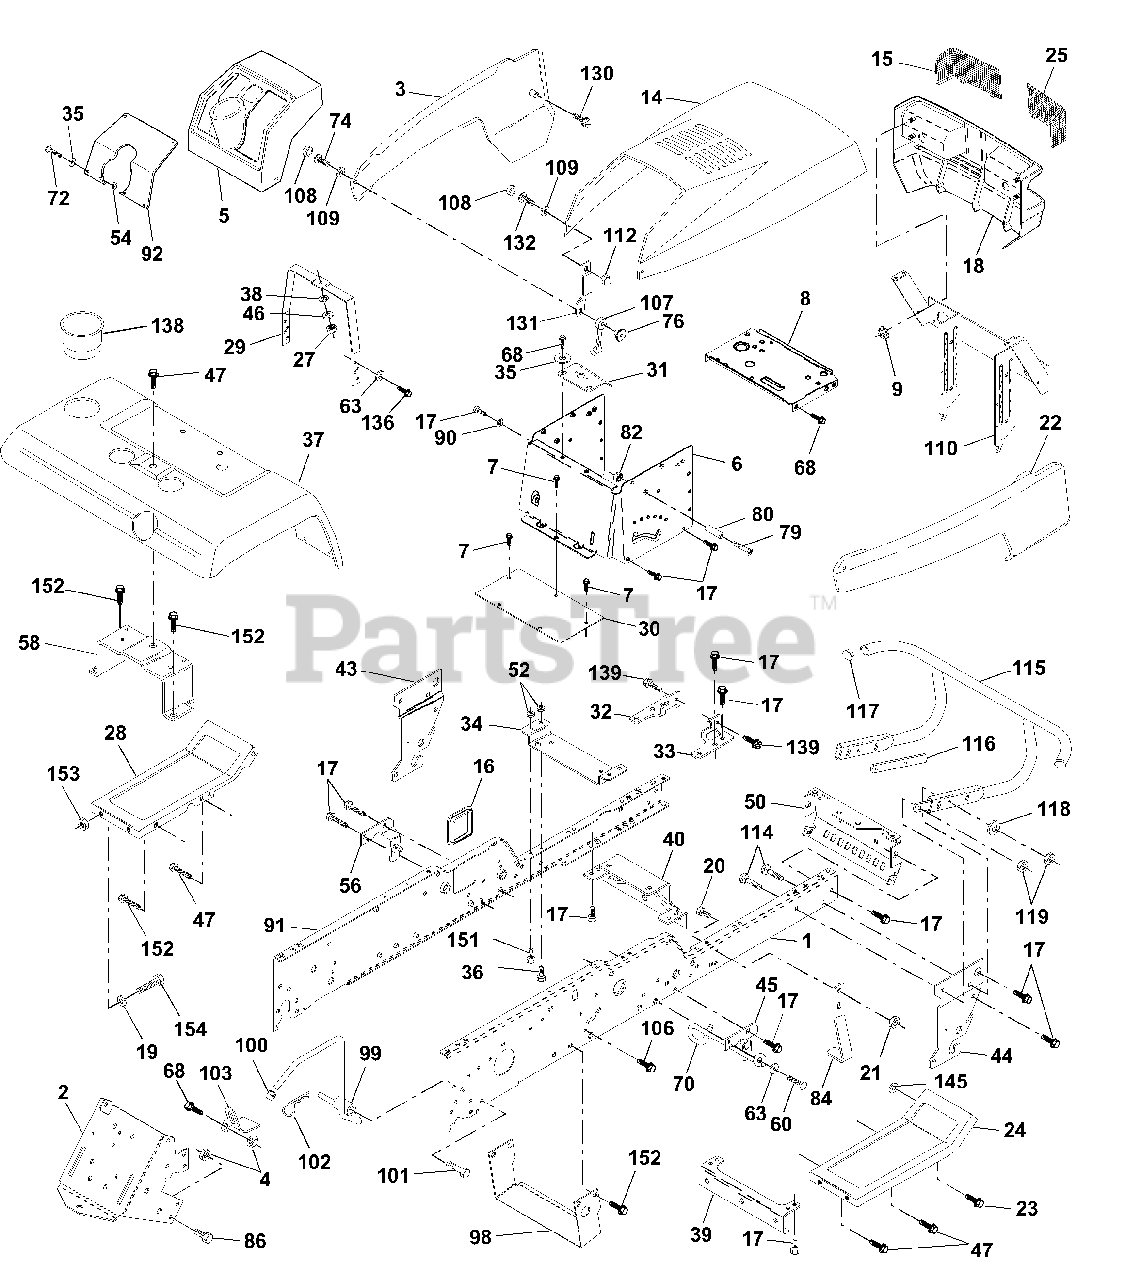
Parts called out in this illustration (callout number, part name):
1	Rail, Frame RH
2	Drawbar, Gt
3	Panel Asm., Side LH
4	Nut, Crownlock 7/16-14 Unc
5	Dash, Plastic Black
6	Dash 1-PCS, Lower
7	Screw, Thd Cut 1/4-20 x 1/2
8	Support, Battery
14	Hood Asm., Pnt
15	Lens, Headlight LH
16	Cover, Access
17	Screw 3/8-16 x 3/4
19	Washer 13/32 x 13/16 x 12 Ga.
20	Bolt, Fin Hex 3/8-16 x 1
21	Nut, Crownlock 3/8-16 Unc
22	Panel Asm., Side RH
23	Screw 3/8-16 x 1/2
24	Footrest, RH
25	Lens Headlight RH
27	Nut Fin Hex 1/4-20
28	Footrest, LH
29	Bracket, Support Dash
31	Brace, Support Steering
32	Bracket Asm., Frame Pivot Lh
33	Bracket Asm., Frame Pivot Rh
34	Bracket, Engine Support Rear
35	Washer 11/32 x 11/16 x 16 Ga.
36	Bolt, Fin Hex 5/16-18 x 3/4
37	Fender, Pnt.
38	Washer, Lock 1/4
39	Bracket, Axle Front
40	Bracket, Support Axle/Engine
43	Bracket, Spnsn Front Lh
44	Bracket, Spnsn Front Rh
45	Bracket Asm., Susp Chassis Rh
46	Washer 9/32 x 3/4 x 16 Ga.
47	Screw Thdrol 3/8-16 x 1/2
50	Bracket, Chassis Front
52	Locknut, Hex W/Ins 5/16-18 Unc
54	Nut 5/16-18
56	Bracket Asm., Susp Chassis Lh
58	Bracket Asm., Fender
60	Screw 3/8-16 x 1-1/4
63	Washer 13/32 x 1 x 14 Ga.
68	Screw, Thdrol 5/16-18 x 1/2
70	Guide, Belt Mid Span
72	Screw, Mach Trhd 5/16-18 x 3/4
74	Screw, Machine #10-24
76	Nut, Weld #10-24
79	Screw, Machine #10-24 x 1/4
80	Spacer, Split
82	Nut #10-24
84	Stop, Over Center 44" 20/23" T. 94
86	Bolt, Fin Hex 7/16-14 Unc x 1
90	Washer, Lock External Tooth 3/8
91	Rail, Frame Lh
92	Plate, Silkscreen Dash
98	Bracket Chassis Skid
99	Rod Asm. Bypass
100	Cap Brake Parking Black
101	Screw Thdrol. 3/8-16 x 1-3/4
102	Retainer Spring 1"
103	Bracket Lock Bypass
106	Screw Thdrol. Hex Hd Zinc Mur
107	Latch, Chute Blk
108	Cap, Snap Black
109	Cap, Washer Snap
110	Pivot Asm. Grille/Hood Husq. VGT
112	Nut, Acorn, Hex #10-24
114	Bolt, Carriage 3/8-16 x 1-1/4
115	Bumper Asm.
116	Bracket Extension Bumper
117	Plug Plastic
118	Washer 13/32 x 13/16 x 16 Ga.
119	Nut Crownlock 3/8-16 UNC
130	Screw HWHD Hi-Lo #13-16 x 3/4
131	Bracket Support Hood/Panel YP
132	Screw Truss Hd. #10-24 x 3/8
136	Screw 3/8-16 x 3/4
138	Cupholder YTGT Grey
139	Bolt, Shoulder 5/16-18 TT
145	Washer Flat 13/32 x 7/8 x 16 Ga.
151	Screw 5/16-18 x 3/4
152	Screw 3/8-16 x 3/4
153	Nut Crownlock 3/8-16 Unc
154	Bolt Hex Fin 3/8-13 x 1
